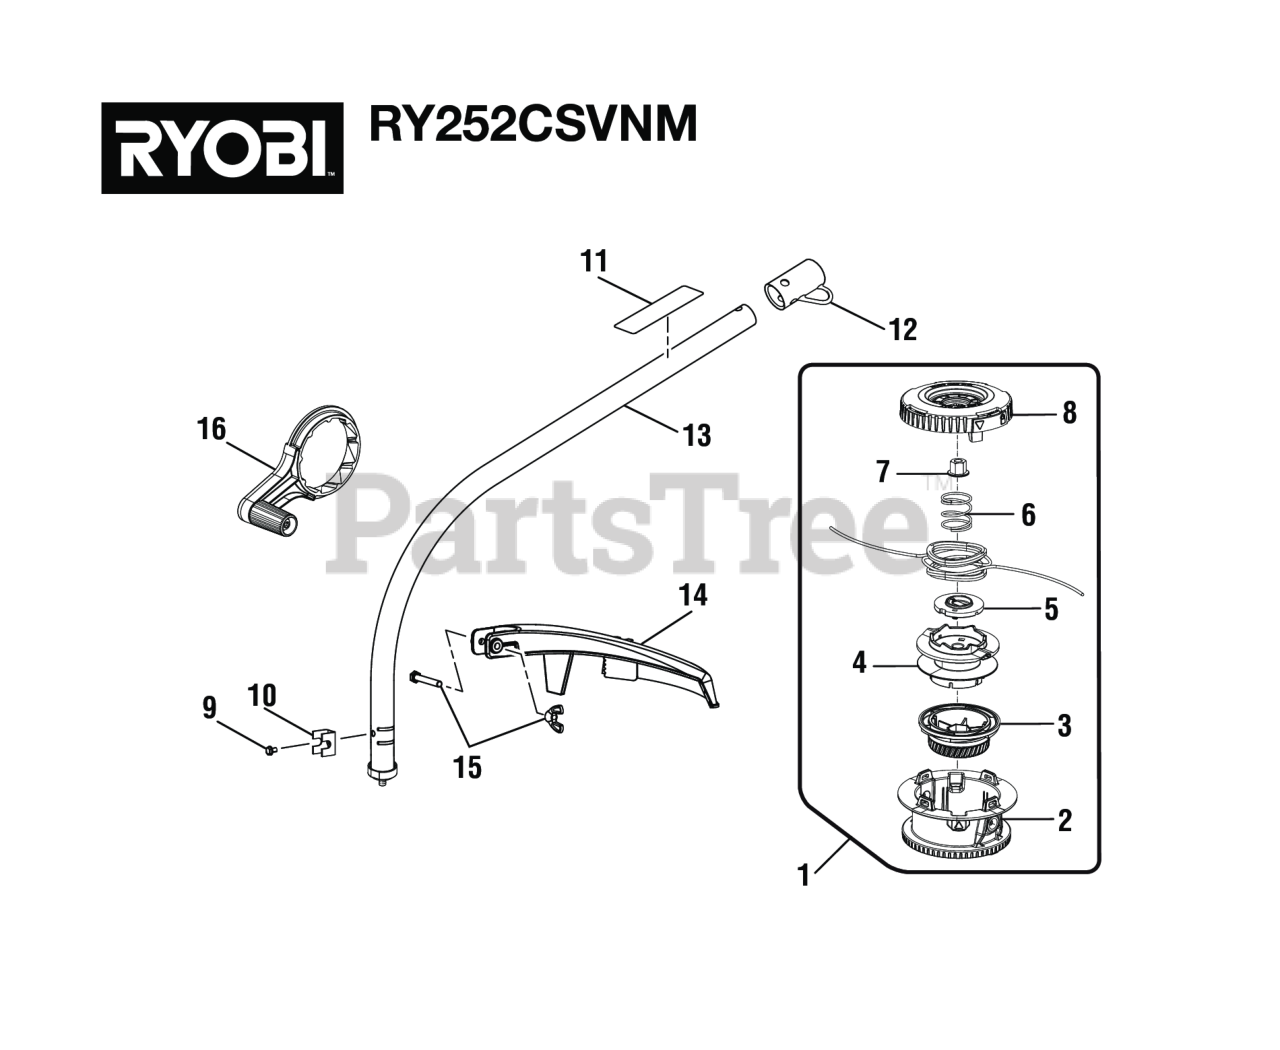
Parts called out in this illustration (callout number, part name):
1	Trimmer Head Assembly (.095) (Inc. Key Nos. 2-8)
2	Bump Head
3	Bump Knob (Green)
4	Spool Assembly
5	String Guide
6	Compression Spring
7	Flange Nut (M8)
8	Locking Assembly
9	Screw (#10-32 x 3/8 in., Hex Washer Hd. S.T.)
11	Warning Icon Label
12	Storage Hanger Cap
13	Curved Shaft Assembly (Inc. Key Nos. 9-12)
14	Grass Deflector Assembly
15	Fastener Parts Kit
16	Crank Handle
